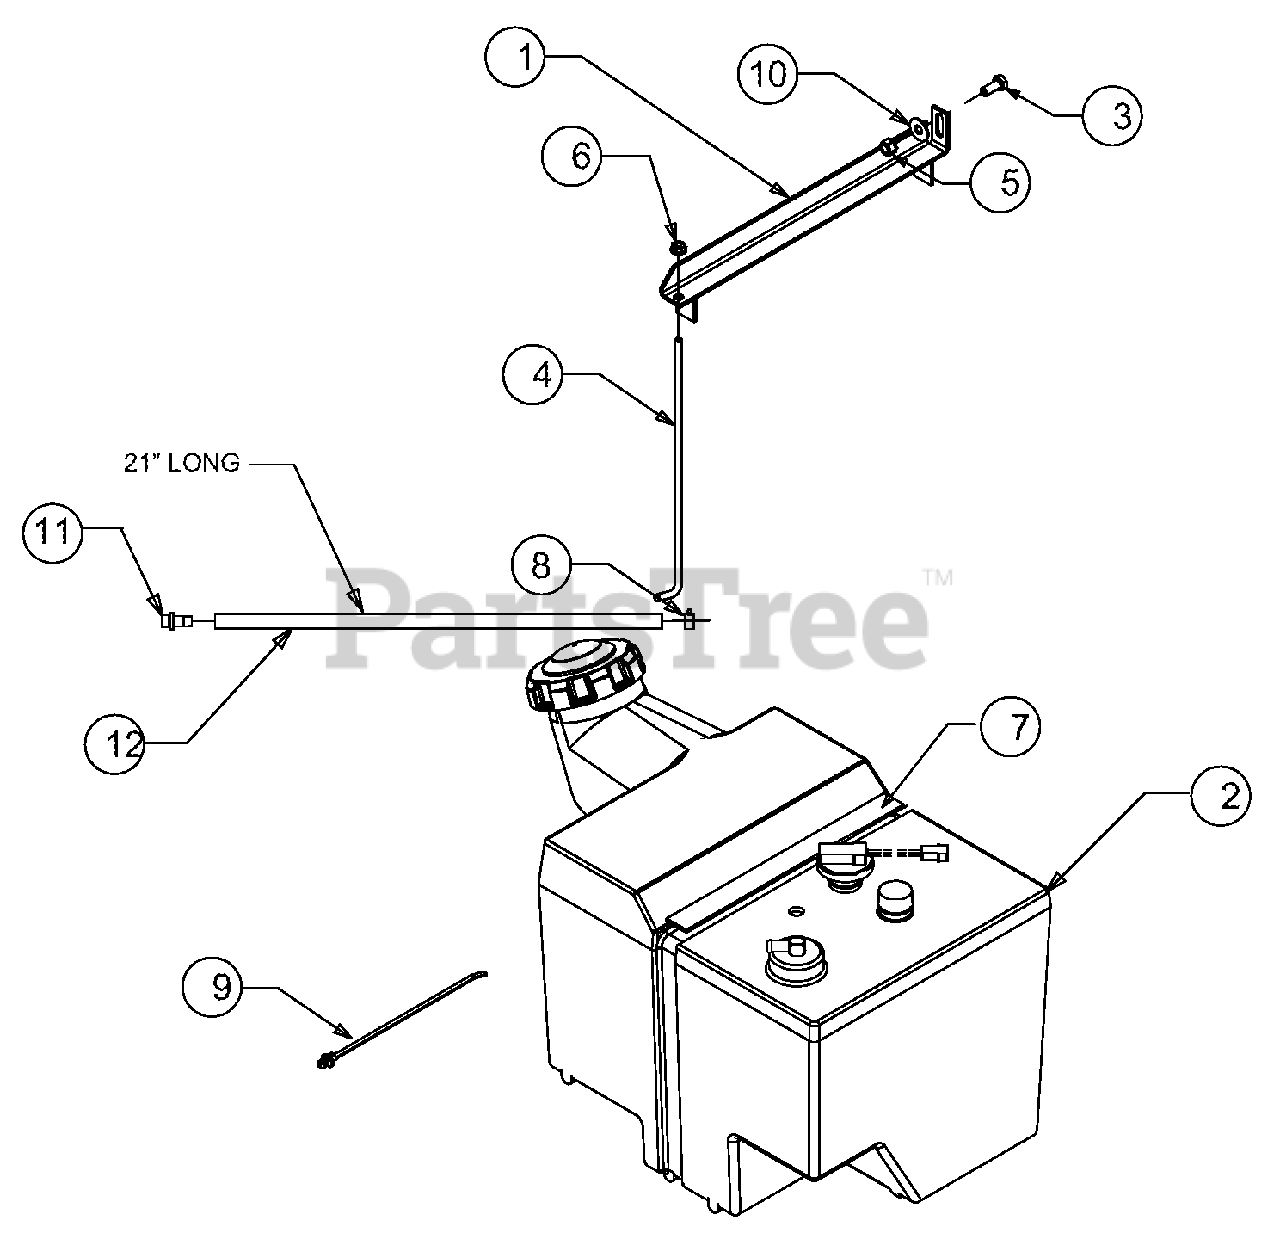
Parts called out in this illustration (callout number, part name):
1	Bracket Assembly, Fuel Tank
2	Tank Assembly, Fuel
3	Hex Screw, 5/16-18 x .75
4	Hold-down Rod, Fuel Tank
5	Sems Nut, 5/16-18
6	Nut, Flange Lock, 1/4-20
7	Gasket, Fuel Tank
8	Clamp, Hose
9	Cable Tie, 19 x 8.39
10	Washer, .349 x .879 x .063
11	Vent, 3/8 Dia.
12	Hose, Fuel Line
